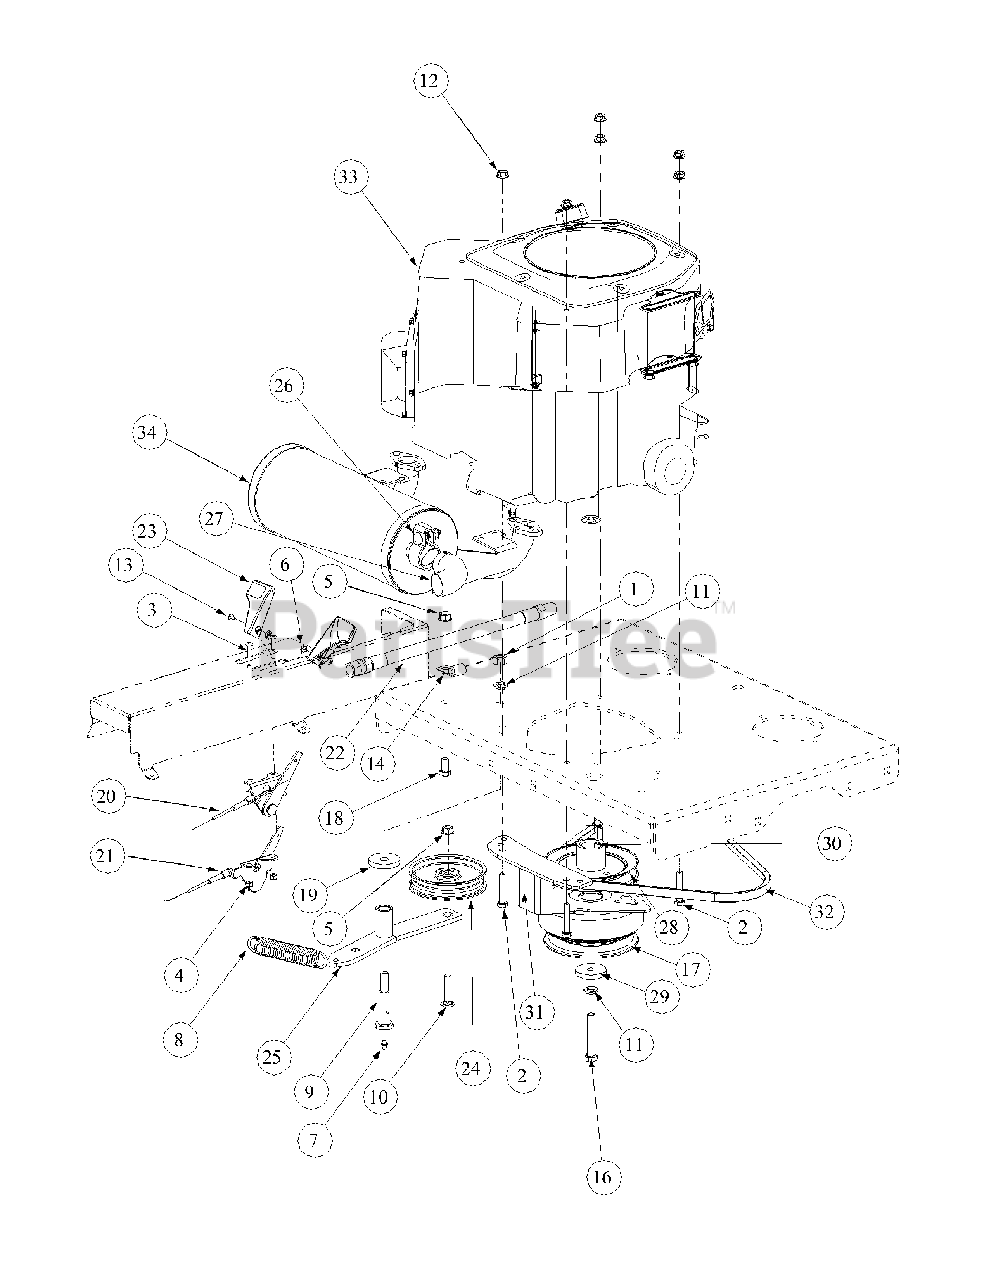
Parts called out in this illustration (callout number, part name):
1	Hex Nut, 7/16-14
2	HHCS, 5/16-18, 1-3/4
3	Round Hd. Machine Screw, 10-32 x 3/4
4	Lock Nut, Nylon Insert, 10-32
5	Flange Lock, Hex Nut, 3/8-16
6	Nut Washer, W/Star, 8-32
7	Grease Fitting, 1/4-28 x 3/16
8	Extension Spring, 1.0 OD x 5.125
9	Shoulder Screw, 7/16-14
10	Hex Carriage Screw, 3/8-16, 1.75
11	Lock Washer, 7/16
12	Hexflange Lock Nut, 5/16-18
13	Machine Screw, 8-32, .375
14	Clip, Heat Shield Cable
16	Capscrew, 7/16-20 x 2.50
17	Clutch Brake, 1.125 ID
18	Hex Cap Screw, 3/8-16, .750
19	Flat Washer, 7/16 ID x 1.75 OD x .25
20	Choke Control Cable
21	Throttle Control Cable
22	Oil Drain Hose
23	Control Throttle Knob
24	Flat Pulley with Flanges
25	Engine Idler Arm Assembly includes:
26	Tube Clamp, 1.375
27	Muffler Accessory Exhaust Tube
28	Pump Drive Pulley
29	Flat Washer, 7/16 ID x 1.75 OD x .25
30	Key, 1/4 x 1/4 x 3
31	Retainer Clutch Assembly, Ogura
32	Belt, 51.2 Lg
33	Engine, 25HP Kohler
34	Muffler
